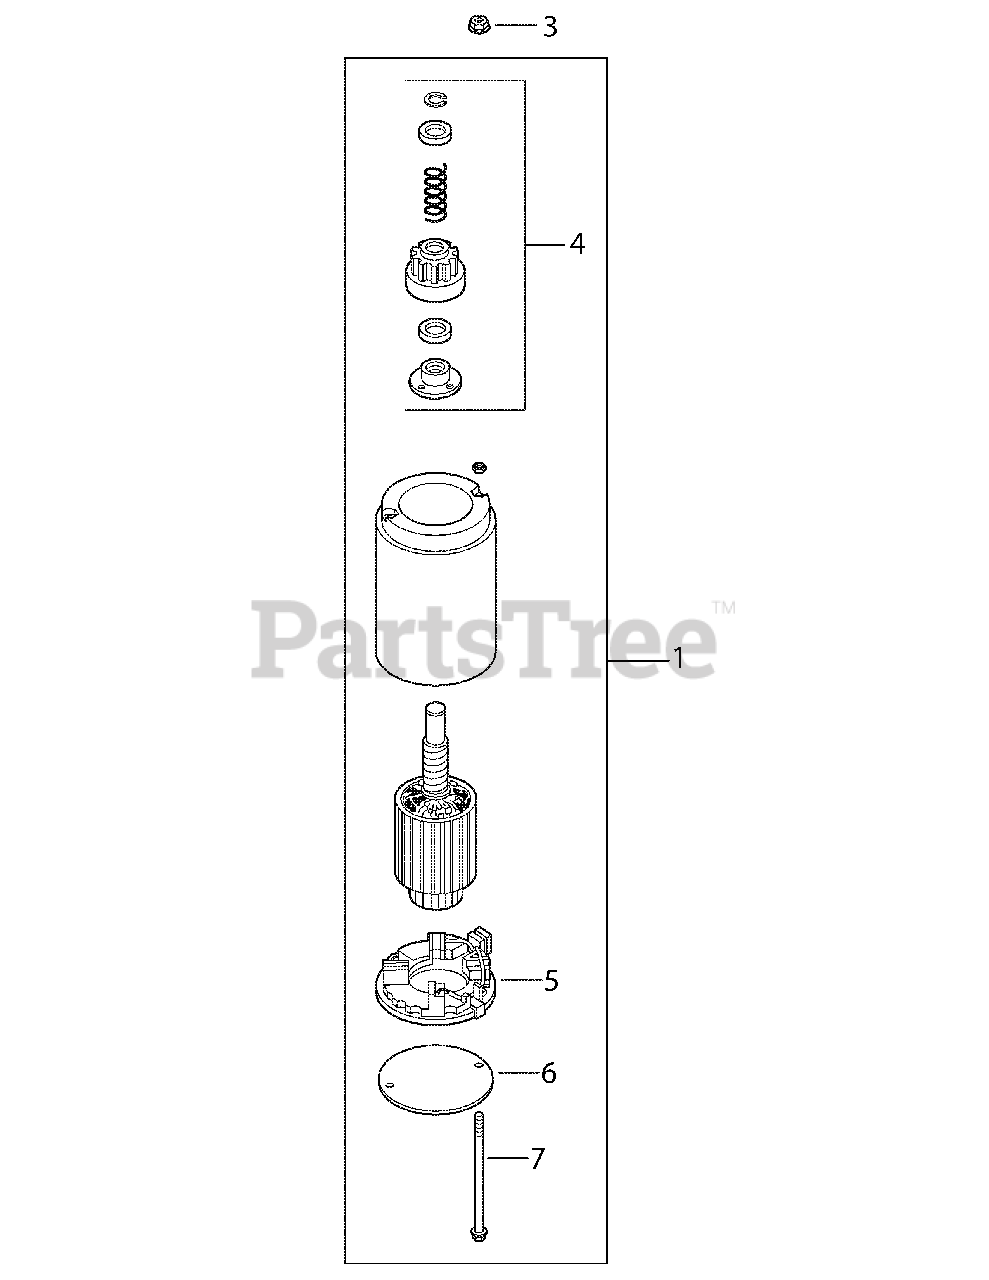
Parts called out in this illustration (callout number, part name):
1	Starter Assembly (Inc. 4-7)
3	Free Spinning Flg. Nut, #10-24
4	Drive Kit (J.E.)
6	Drive End Cap (J.E.)
